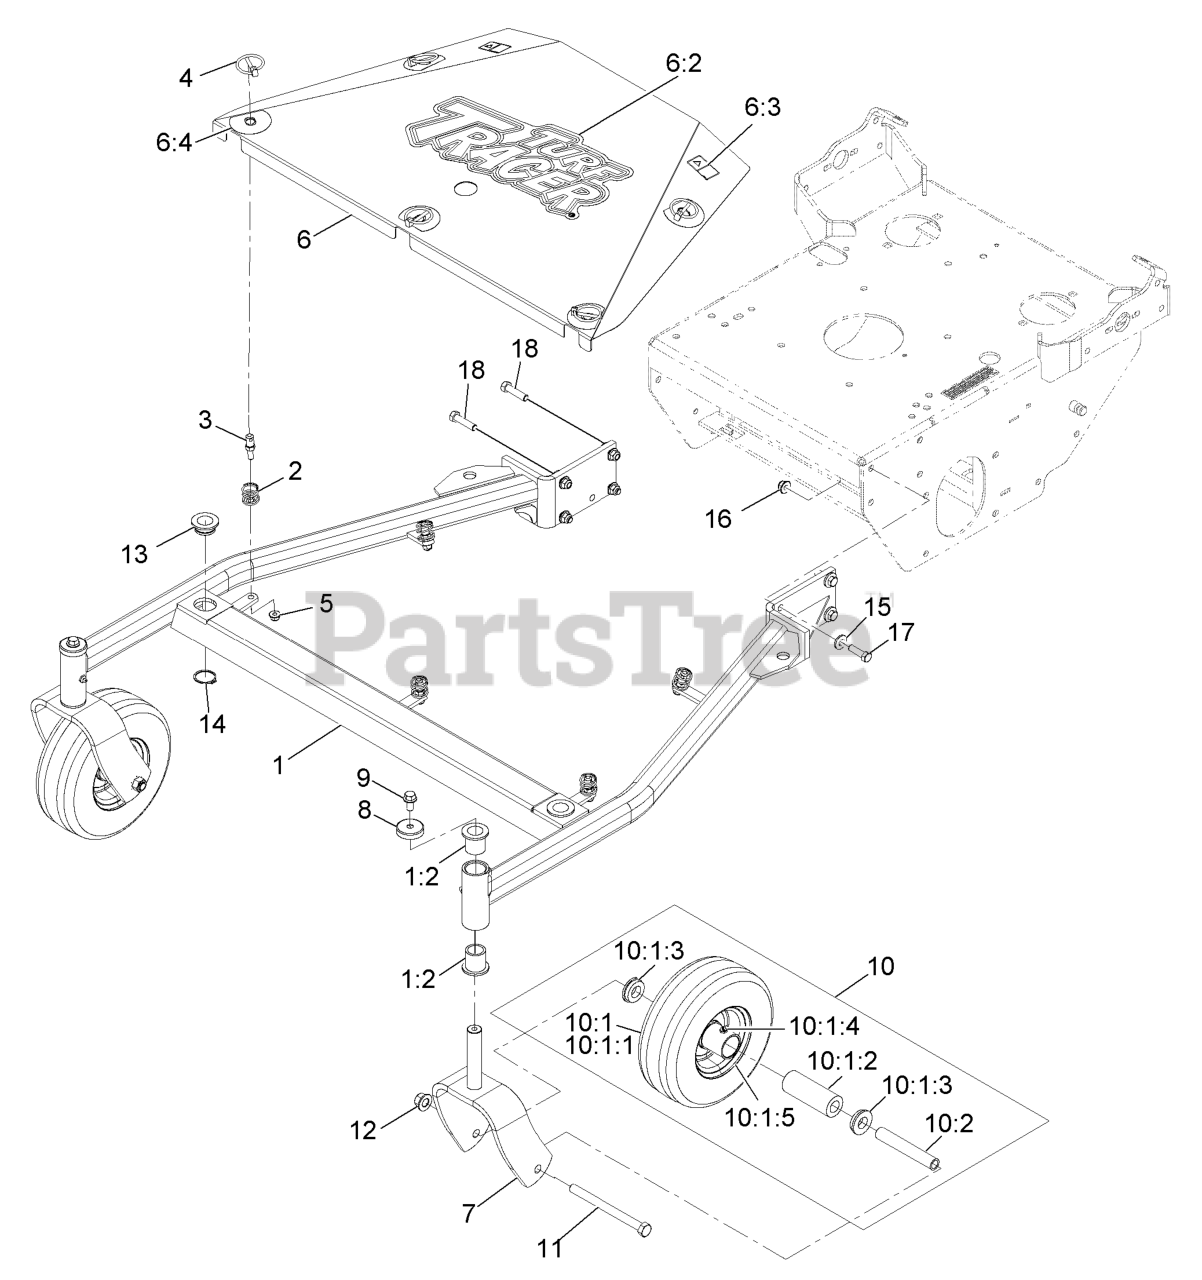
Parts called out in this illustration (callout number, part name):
1	ASM, FRAME W/ BUSHINGS, 4
1:2	BEARING-FLANGED
3	PIN-SPRING
4	PIN-LYNCH
5	NUT-HF, NI
6	ASM, SHIELD W/ DECALS, 48
6:2	DECAL,TTH MODEL
6:3	DECAL-WARNING
6:4	DECAL-SCRATCH COVER
7	FORK, CASTER
8	CAP, DUST
9	SCREW-HHF
10	KIT, SP CASTER WHEEL REPL
10:1	Wheel And Tire ASM
10:1:1	Tire
10:1:2	BEARING
10:1:3	BUSHING
10:1:4	FITTING-GREASE
10:1:5	Wheel
11	SCREW-HH
12	Nut-Lock 1/2-13
13	BUSHING-DECK
14	RING-RETAINING
15	WASHER-BELLEVILLE
16	NUT-HF, NI
17	SCREW-HH
18	SCREW-HH
